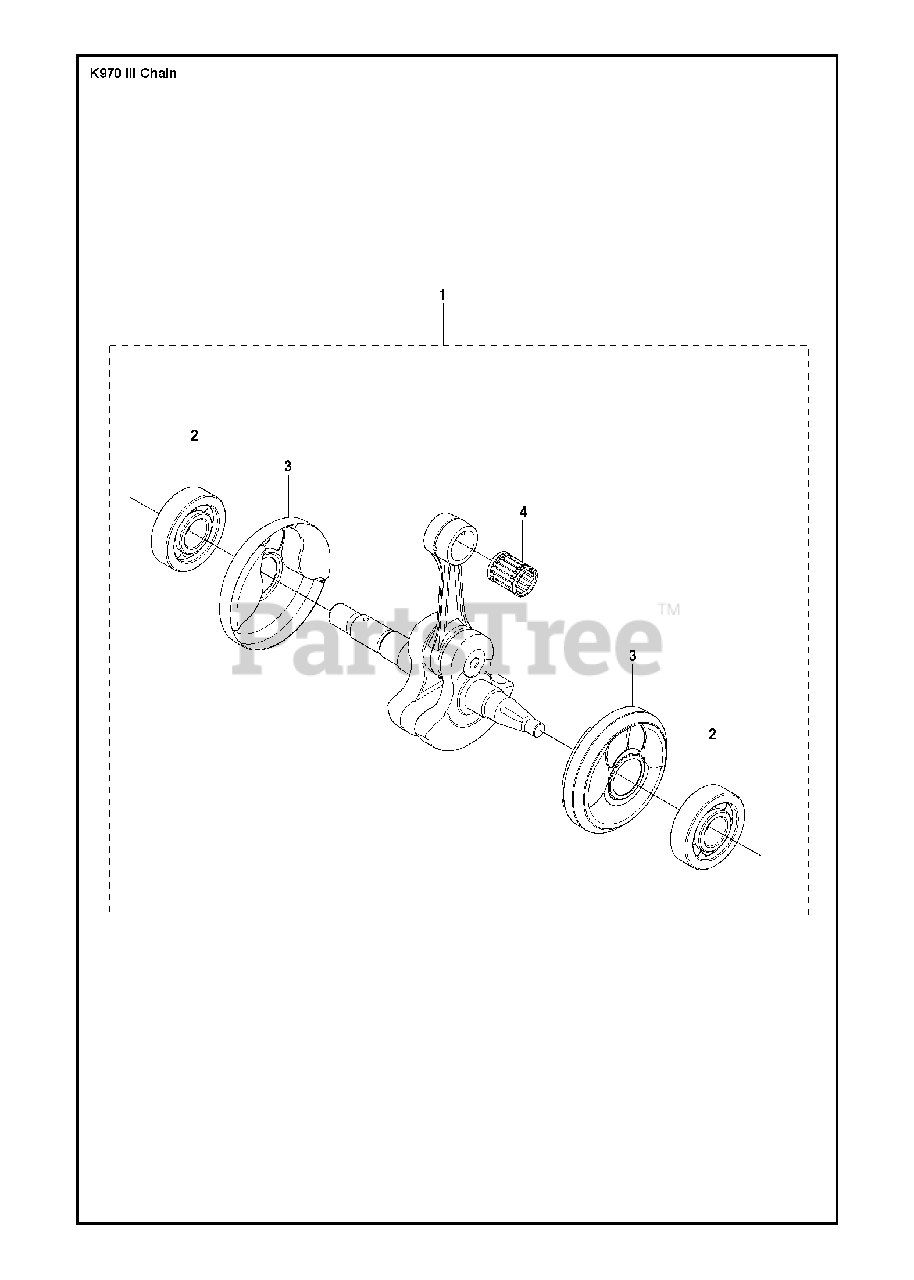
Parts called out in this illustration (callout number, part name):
1	CRANKSHAFT ASSYIncl. 2 - 4
2	BALL BEARING
4	NEEDLE BEARING
